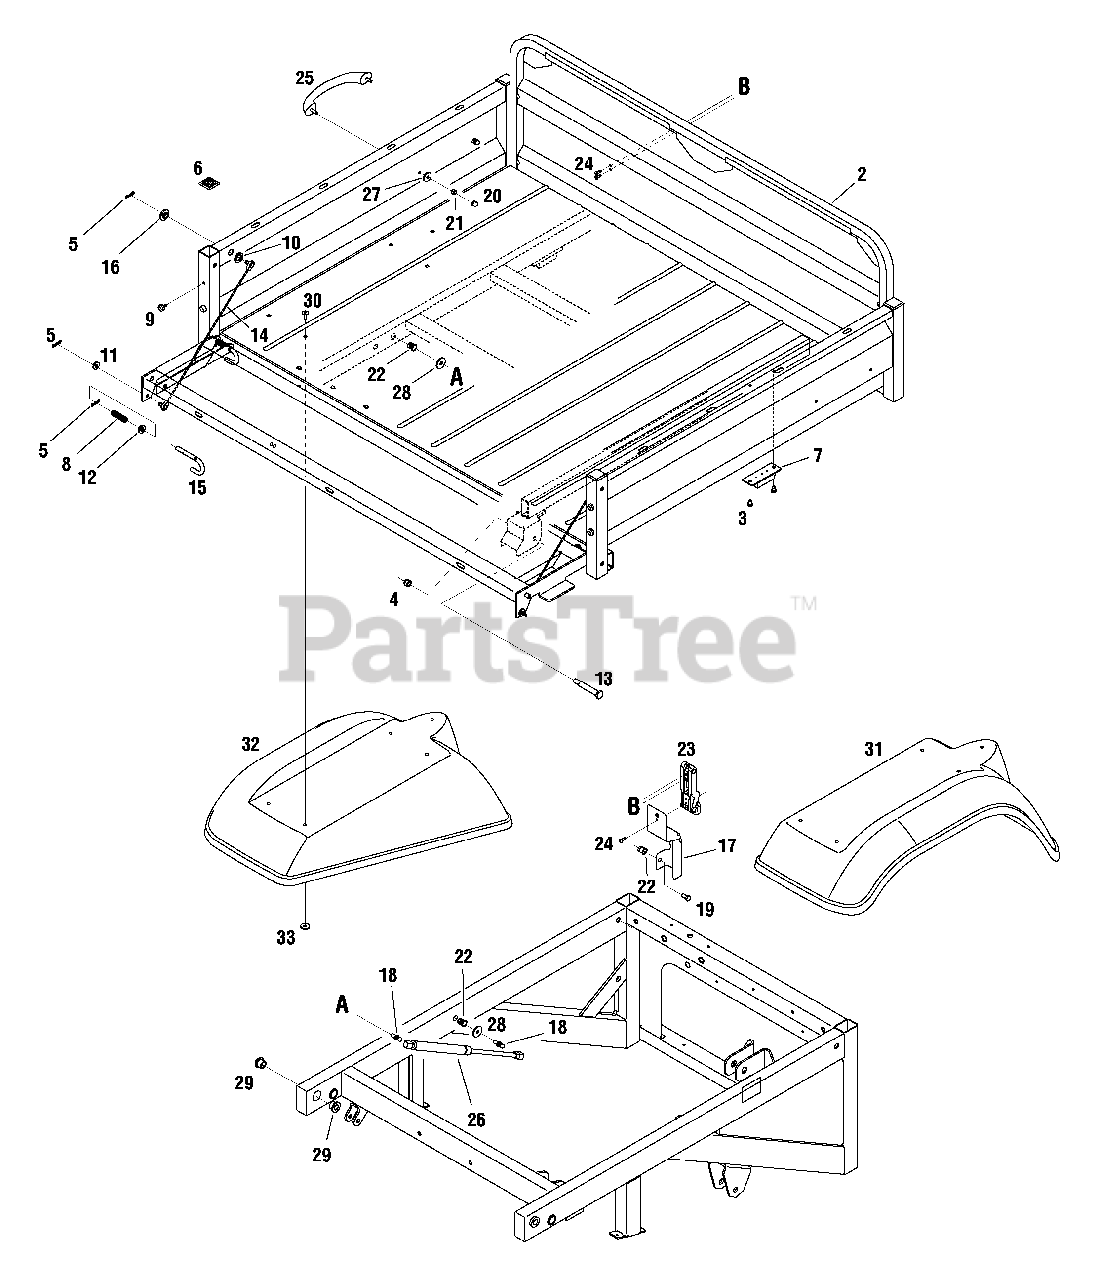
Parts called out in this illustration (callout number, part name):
1	Tailgate Assembly
2	Bed Assembly
3	Screw, Self-tapping, 1/4-20 x 0.500
4	Nut, Nylon Hex Lock, 3/8-16
5	Cotter Pin, .072 Dia x 1.13
7	Bumper, Extension Suspension
8	Compression Spring, .406 x .531 x
9	Bumper, .62 x .3
10	Washer, Flat, .64 ID x 1.0 x .12
11	Washer, Flat, .344 x .750 x .120
12	Washer, Flat, .407 x .812 x .135
13	Screw, Shoulder, 1/2 x 2.5
14	Cable, LIft 16.16 LG
15	Handle, Deck Release
16	Spacer, Shoulder .625 x .324 Dia
17	Bracket, Bed Latch Base
18	Stud, Ball 5/16-18
19	Hex Screw, 5/16-18 x .625, Gr5
20	Nut, Acorn 1/4-20 w/o Lock
21	Nut, Hex Lock, 1/4-20
22	Nut, Insert 5/16-18
24	Pop Rivet, 3/16
25	Handle, Bag w/Screw
26	Spring, Gas .91 Stroke
27	Washer, Flat .265 x .938 x .120
28	Washer, Flat .344 x 1.125 x .120
29	Flange Bearing, .51
30	Pop Rivet, .188
31	Fender, Rear RH, Camo
32	Fender, Rear LH, Camo
33	Flat Washer, .194 x .62 x .063
